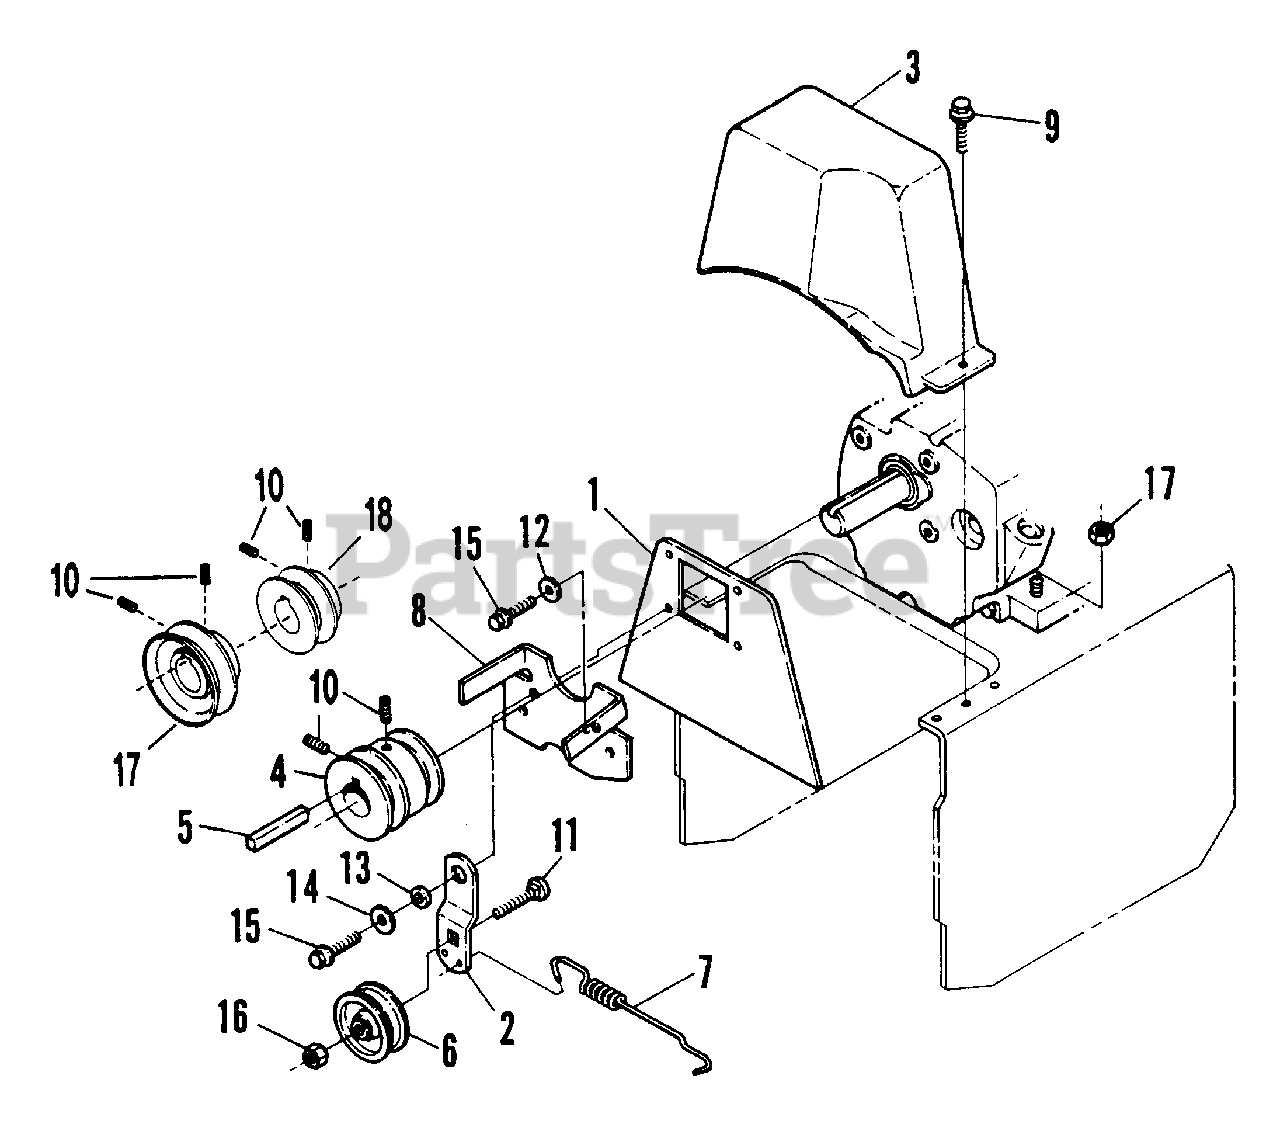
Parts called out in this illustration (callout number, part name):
1	GUARD, Engine
2	ARM, Idler
3	COVER, Belt
4	SHEAVE, Engine
5	KEY, 1/4 x 2" Square
6	IDLER
7	SPRING, Idler
8	FINGER, Belt
9	SCREW, 1/4-20 x 3/8" Self-Tapping
10	SCREW, 5/16-18 x 5/16" Socket Head Set
11	BOLT, 3/8-16 x 1-1/2" Carriage
12	WASHER, 5/16 Flat
13	SPACER
14	WASHER, 3/8" Flat
15	SCREW, 5/16-24 x 5/8" Hex Head Cap
16	NUT, 3/8-16 Hex Top Lock
17	PULLEY, Traction
18	PULLEY, Traction
